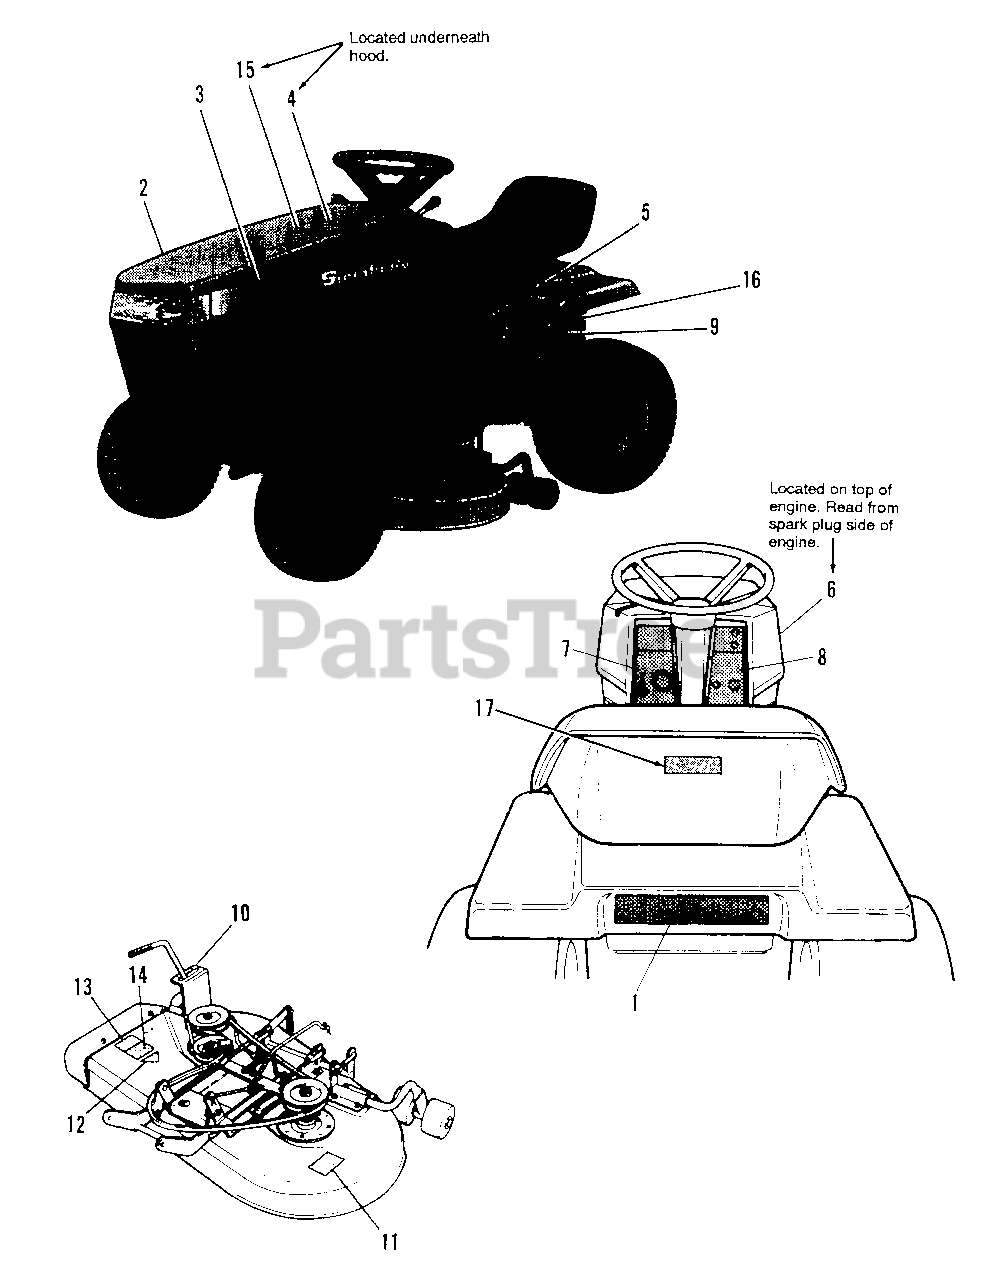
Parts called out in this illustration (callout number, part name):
1	DECAL, Simplicity
2	DECAL, Hood, R.H. (Gear models only)
2	DECAL, Hood, R.H. (Hydro models only)
3	DECAL, Hood, L.H. (Gear models only)
4	DECAL Drive Belt
5	DECAL, Shift Pattern (Gear models only)
6	DECAL, 12.5 HP, I/C
7	DECAL, Dash, L.H. Side
8	DECAL, Dash, R.H. Side
9	DECAL, Warning, Fan (Hydro Models only)
10	DECAL, Mower Height
11	DECAL, Danger, Rotating Blade
12	DECAL, OPEI
13	DECAL, Danger, Deflector in Place
14	DECAL, Cutting Width, 36"
15	DECAL, Touch-up Paint
16	DECAL, Tow Valve, (Hydro Model, Mfg. No. 1692156)
17	DECAL, USA
